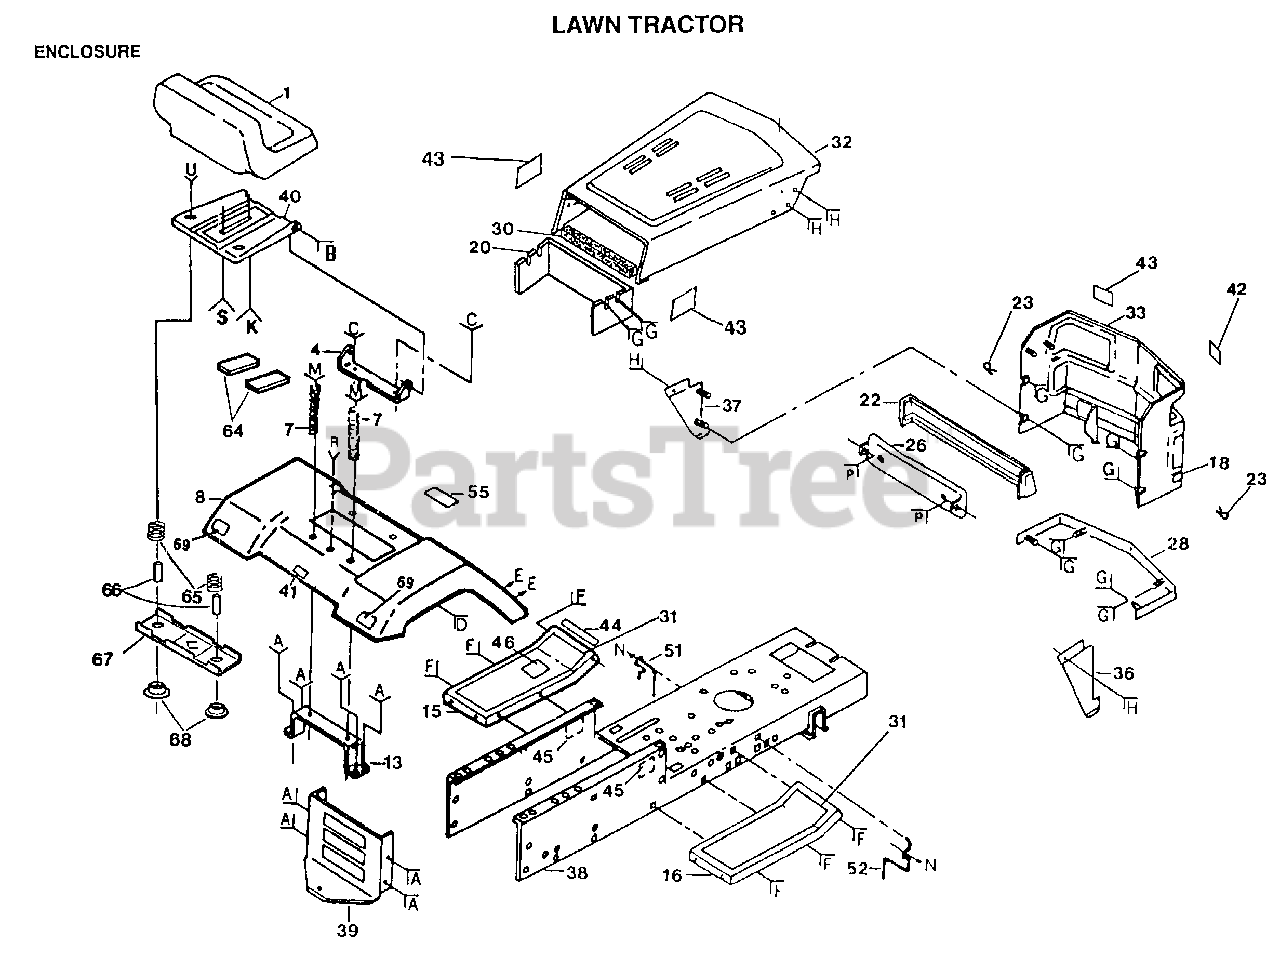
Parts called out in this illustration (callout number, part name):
7	SPRING COMPRESSIO
18	DECAL, HOOD R.H.
20	"SHIELD,HEAT"
23	SPRING.RETAINER
30	FOAM-STRIP LT
31	PAD FOOTREST T
38	CHASSIS ASS'Y
41	"DECAL,FENDER T"
42	"DECAL,GRILL"
43	"DECAL,GRILL HP T"
44	DECAL T
45	DECAL, CHASSIS, SPEED/DECK SIZE
51	BELT GUIDE
52	BELT GUIDE
64	STRIP FORM
65	SPRING COMPRESSED
66	SPACER SPLIT
67	BRKT SWITCH
68	BUSHING
69	REFLECTOR-TAIL YT
